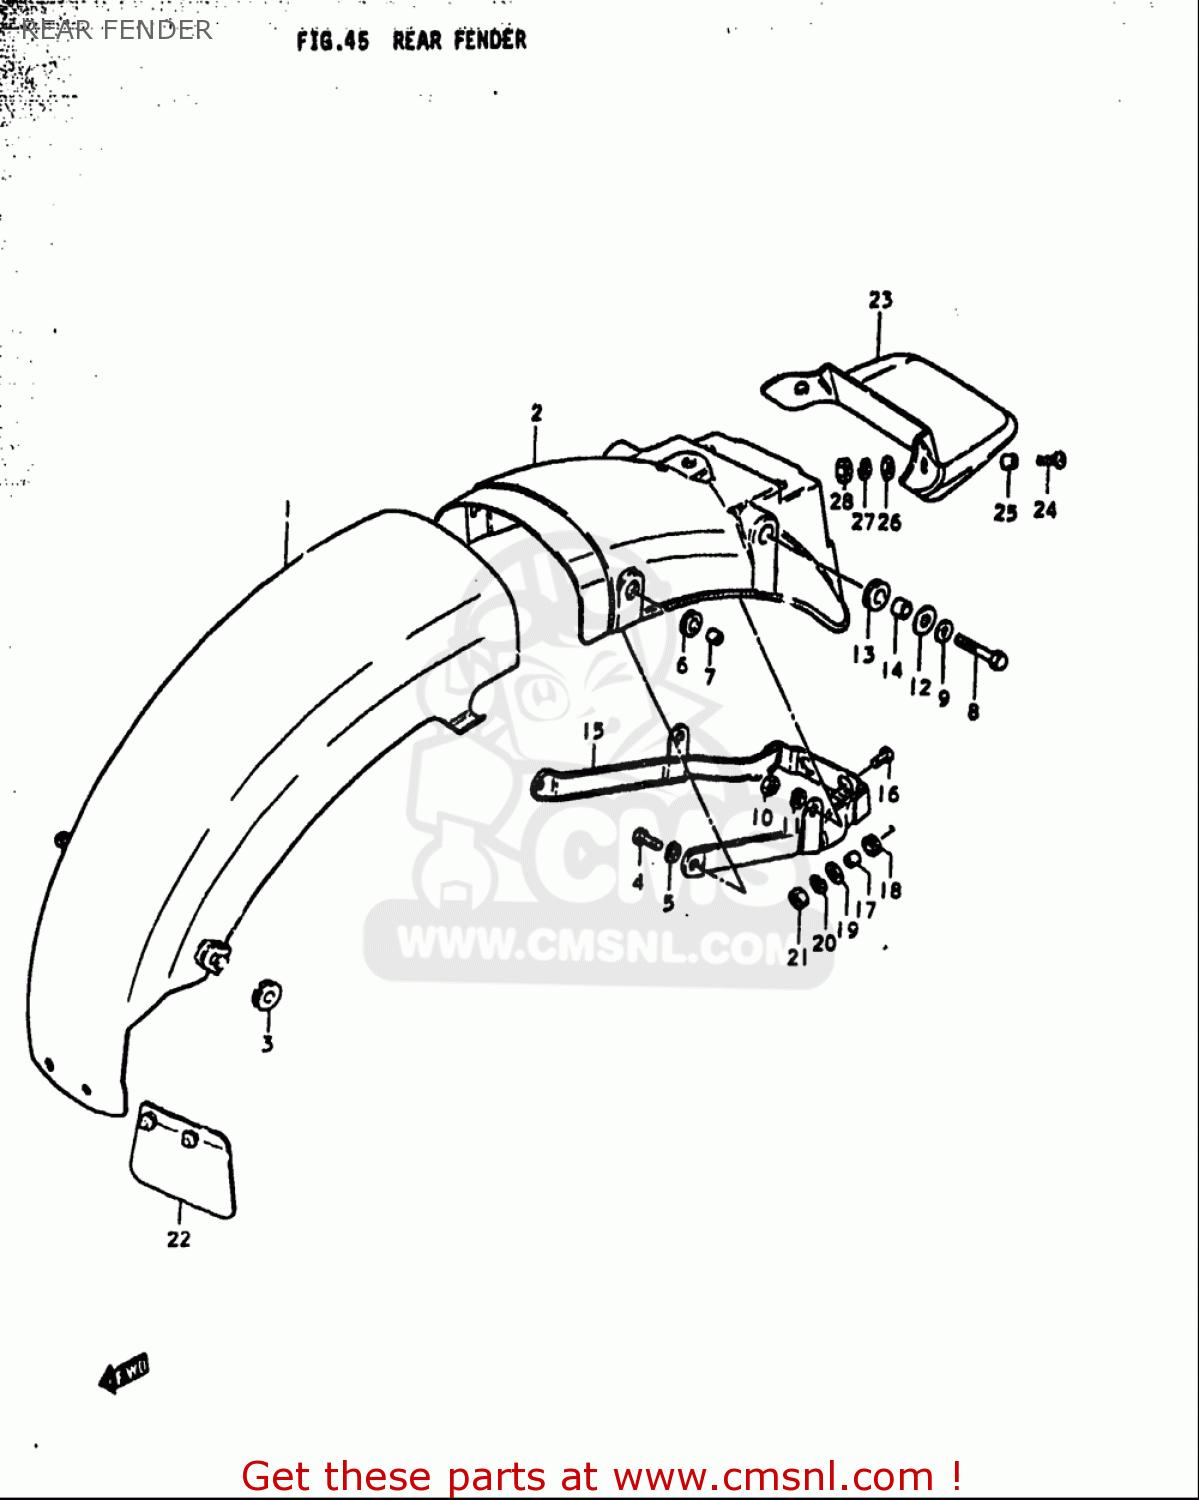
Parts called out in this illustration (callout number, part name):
1	BODY,RR FENDER FR
2	BODY,RR FENDER RR
3	CUSHION
4	BOLT
5	WASHER,LOCK
6	CUSHION
7	SPACER(6.1X9X7.5)
8	BOLT
9	WASHER
10	NUT
11	WASHER,LOCK
12	WASHER(8.5X26X1.2)
13	CUSHION
14	SPACER(8.5X12X7.5)
16	SCREW
17	SPACER(6.5X9X9)
18	CUSHION
19	WASHER(6.5X22X1.6)
20	WASHER,LOCK
21	NUT
22	GUIDE,RR FENDER MUD
24	SCREW(6X16)
25	SPACER(6.2X8.3X5.7)
26	WASHER(6.5X18X1)
27	WASHER,LOCK
28	NUT
